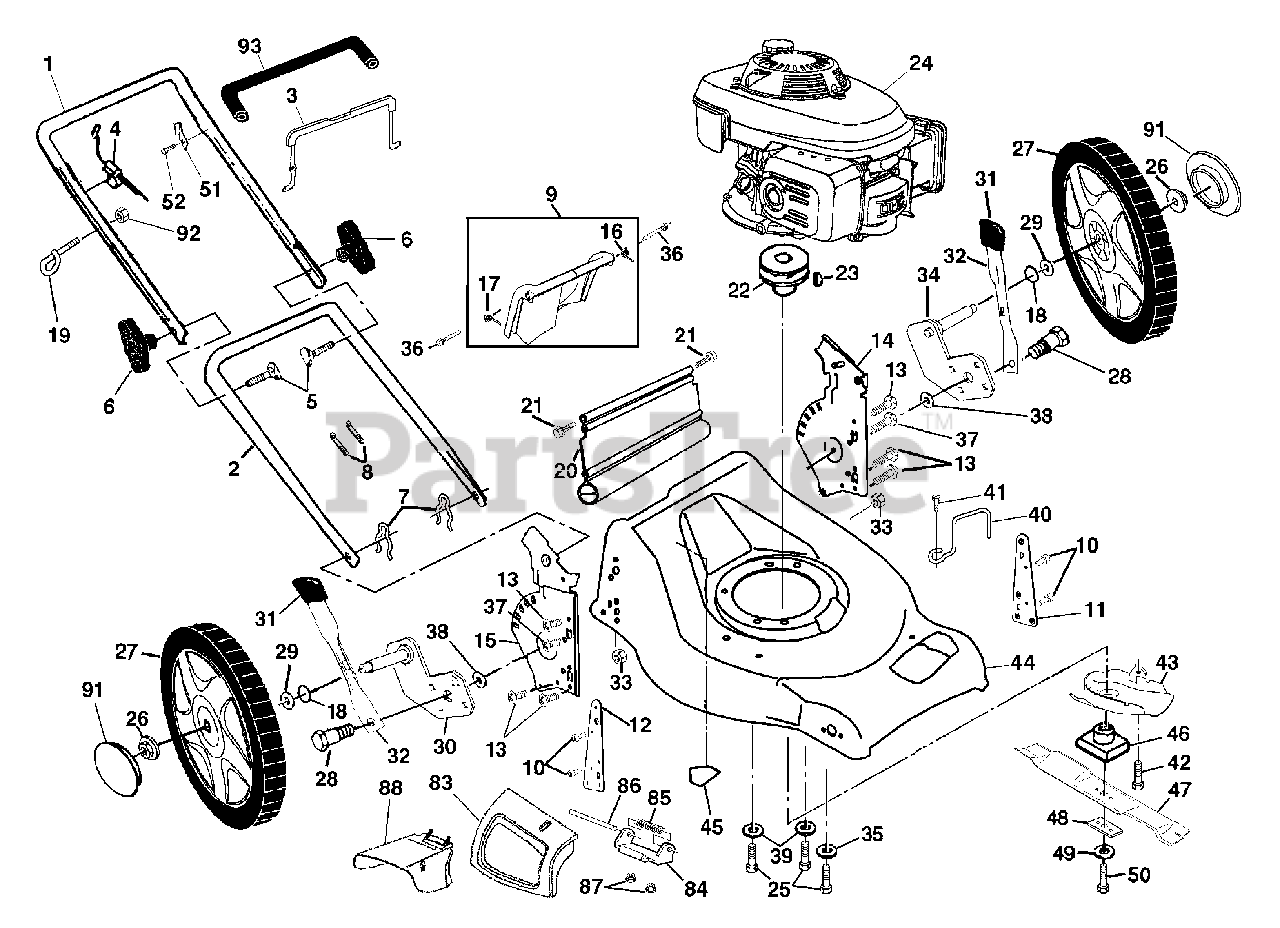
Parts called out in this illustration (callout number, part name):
1	Upper Handle
2	Lower Handle
3	Control Bar
4	Engine Zone Control Cable
5	Handle Bolt
6	Handle Knob
7	Hairpin Cotter
8	Wire Tie
9	Rear Door Kit
11	Support Bracket, LH
12	Support Bracket, RH
13	Screw 1/4-20 x 5/8
14	Handle Bracket Assembly (Left)
15	Handle Bracket Assembly (Right)
16	Spring, LH
17	Spring, RH
18	O-Ring
19	Rope Guide
20	Rear Skirt
21	Hinge Screw 1/4-20 x 1-1/4
22	Engine Pulley
23	Hi-Pro Key
24	Engine, Honda, Model Number GCV160 (Order parts from engine manufacturer)
25	Hex Head Thread Rolling Screw 3/8-16 x 1-1/8
26	Hex Flange Nut
27	Wheel
28	Shoulder Bolt 5/16-18 x .33
29	Washer, Flat 3/8
30	Axle Arm Assembly RR
31	Selector Knob
32	Selector Spring
34	Axle Arm Assembly, LR
37	Thread Cutting Screw w/Sems 5/16-18 x 3/4
40	Keeper, Belt
42	Screw, Belt Cover
43	Belt Cover, Bottom
44	Lawn Mower Housing
45	Danger Decal
46	Blade Adapter
47	Blade, 21"
48	Hardened Washer
49	Helical Washer 3/8-24 x 1-3/8 Grade 8
50	Hex Head Machine Screw 3/8-24 x 1-3/8 Grade 8
51	Bracket, Upstop
83	Mulch Door
84	Hinge Bracket Assembly
85	Spring
86	Rod, Hinge
87	Locknut
88	Clipping Deflector
91	Hubcap
92	Nut, Hex
93	Grip, Foam
